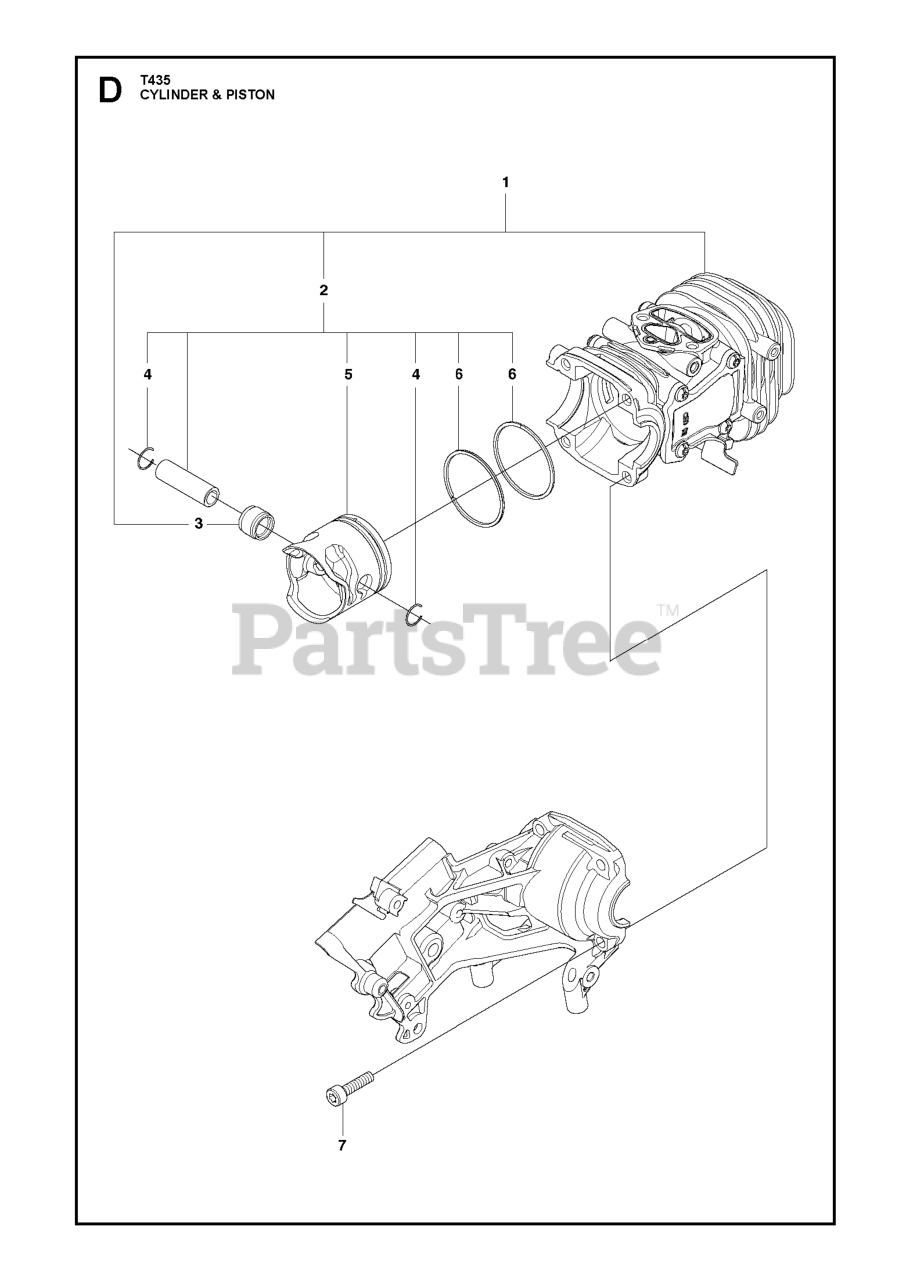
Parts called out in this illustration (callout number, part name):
3	BEARING,ROLLER
6	RING, PISTON
7	BOLT
